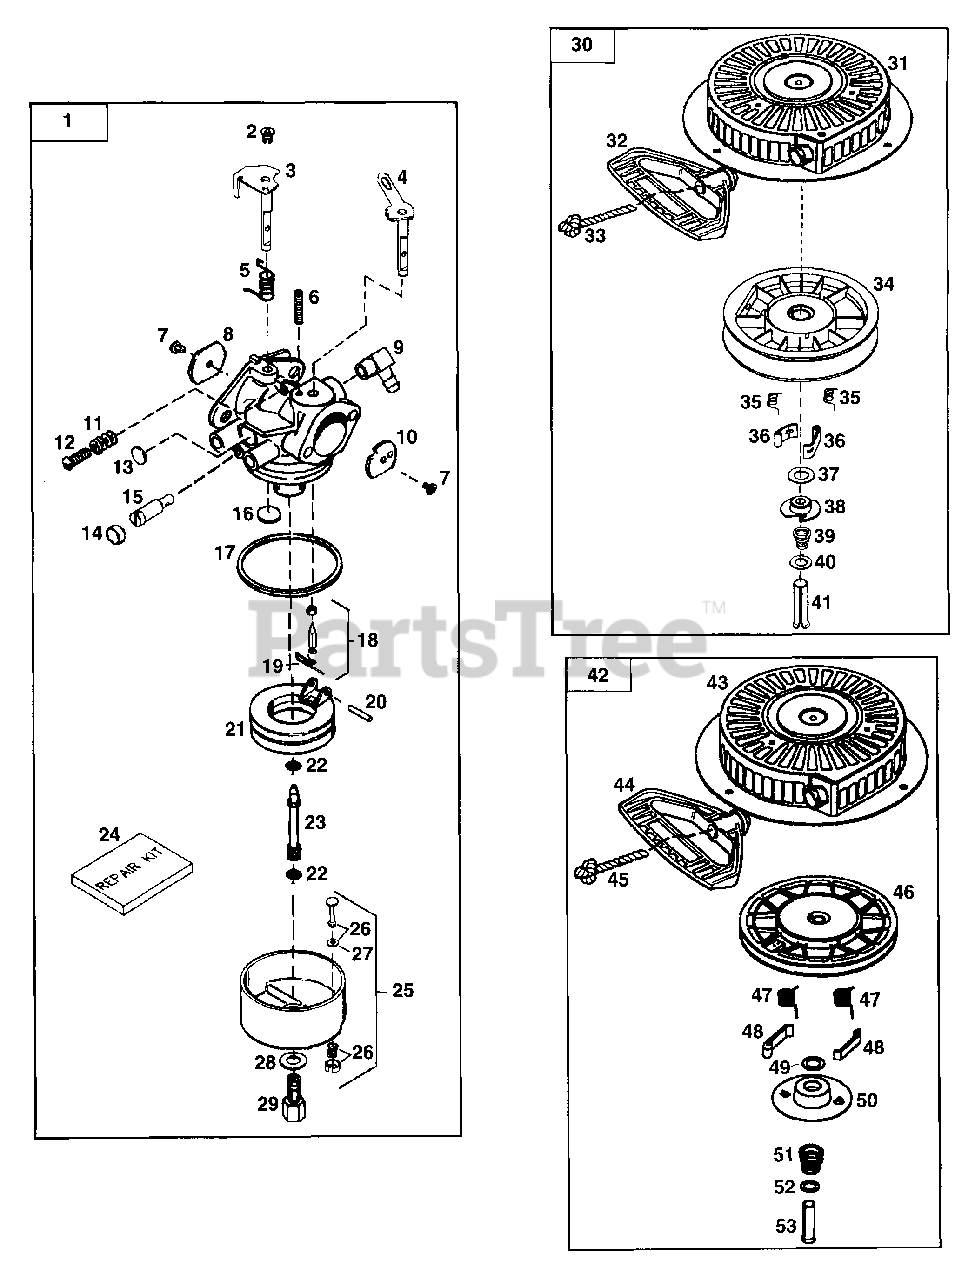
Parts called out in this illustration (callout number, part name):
1	Carburetor Assembly
2	Throttle Link Bushing
3	Throttle Shaft & Lever Assembly
4	Choke Shaft & Lever Assembly
5	Throttle Return Spring
6	Choke Positioning Spring
7	Shutter Screw
8	Throttle Shutter
9	Fuel Fitting
10	Choke Shutter
11	Tension Spring
12	Throttle Crack Screw/Idle Speed Screw
13	Welch Plug, Idle Mixture Well
14	Idle Restrictor Screw Cap
15	Idle Restrictor Screw
16	Welch Plug, Atmospheric Vent
17	Float Bowl O-Ring
18	Inlet Needle, Seat & Clip
19	Spring Clip
20	Float Shaft
21	Float
22	O-Ring, Main Nozzle Tube
23	Main Nozzle Tube
24	Repair kit
25	Float Bowl Assembly
26	Bowl Drain Assembly
27	Drain Plunger Gasket
28	Bowl Nut Washer
29	High Speed Bowl Nut
30	Rewind Starter
31	Starter Housing Assembly
32	Mitten Grip Handle (Not
33	Starter Rope (Length 98" x 9/64" dia.)
34	Pulley & Rewind Spring Assembly
35	Dog Spring
36	Starter Dog
39	Brake Spring
41	Spring Pin
42	Rewind Starter Ass'y
43	Starter Housing Ass'y
44	Mitten Grip Starter Handle
45	Starter Rope (98")
46	Pulley & Rewind Spring Ass'y
47	Dog Spring
48	Starter Dog
51	Brake Spring
53	Spring Pin
